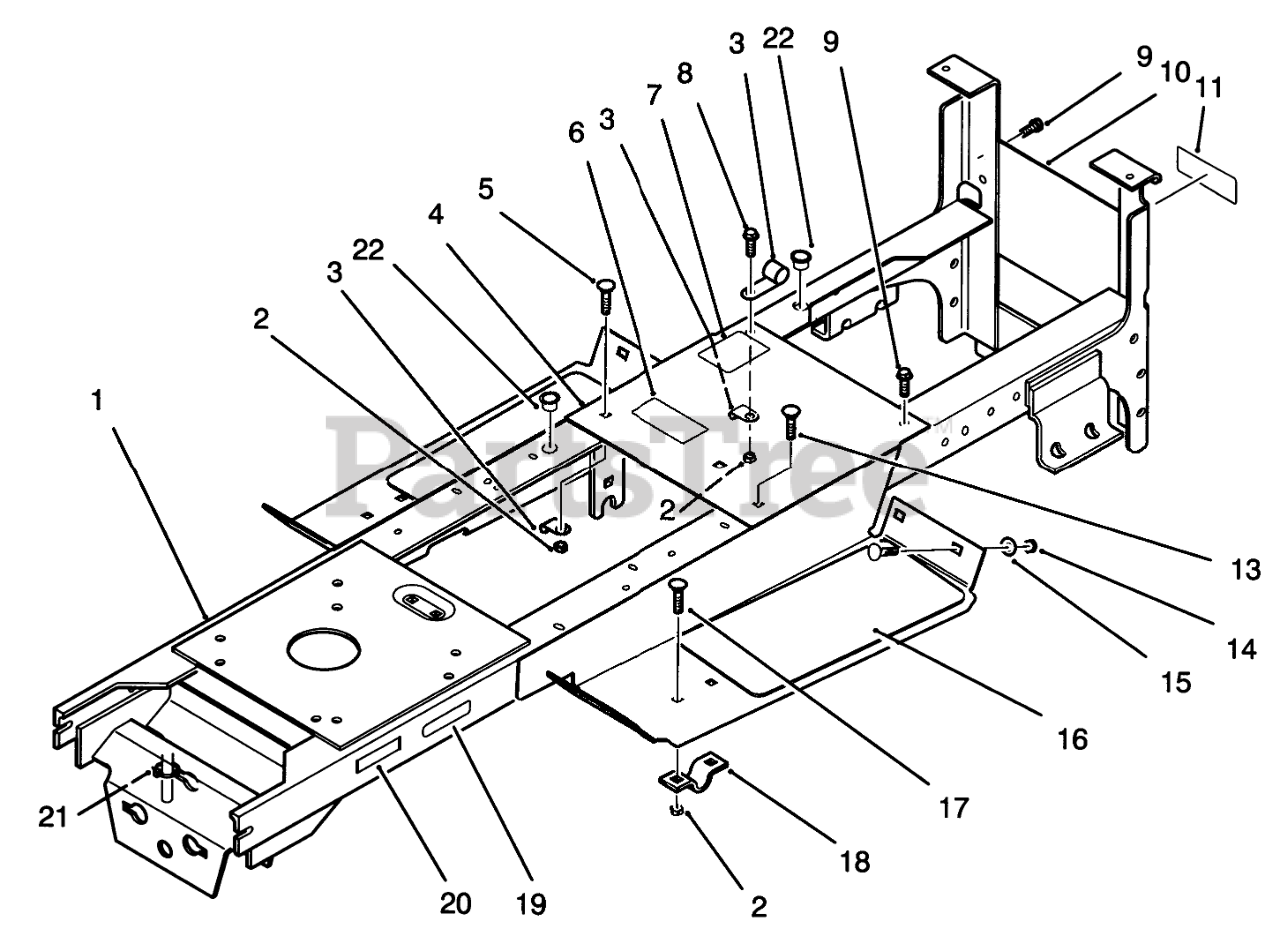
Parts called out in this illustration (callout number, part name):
1	Frame & Safety Decal Assy. (Incl. Ref. #11)
2	NUT-LOCK, NI
3	THROTTLE CONTROL CLP
4	Panel & Safety Decal Assy. (Incl. Ref. #6)
5	Bolt-Carriage
6	DECAL-DANGER
7	DECAL-PARKING BRAKE
8	Bolt
9	Screw
10	PANEL-REAR R
11	DECAL - DANGER
13	SCREW-CARR
14	NUT-HEX
15	WASHER - FLAT YZ
16	PAD FOOTREST
17	NUT-HEX, JAM
18	CLAMP
19	DECAL - BELT INSTR.
20	Decal-Attac-O-Matic
21	PLASTIC TIE
22	BUSHING
